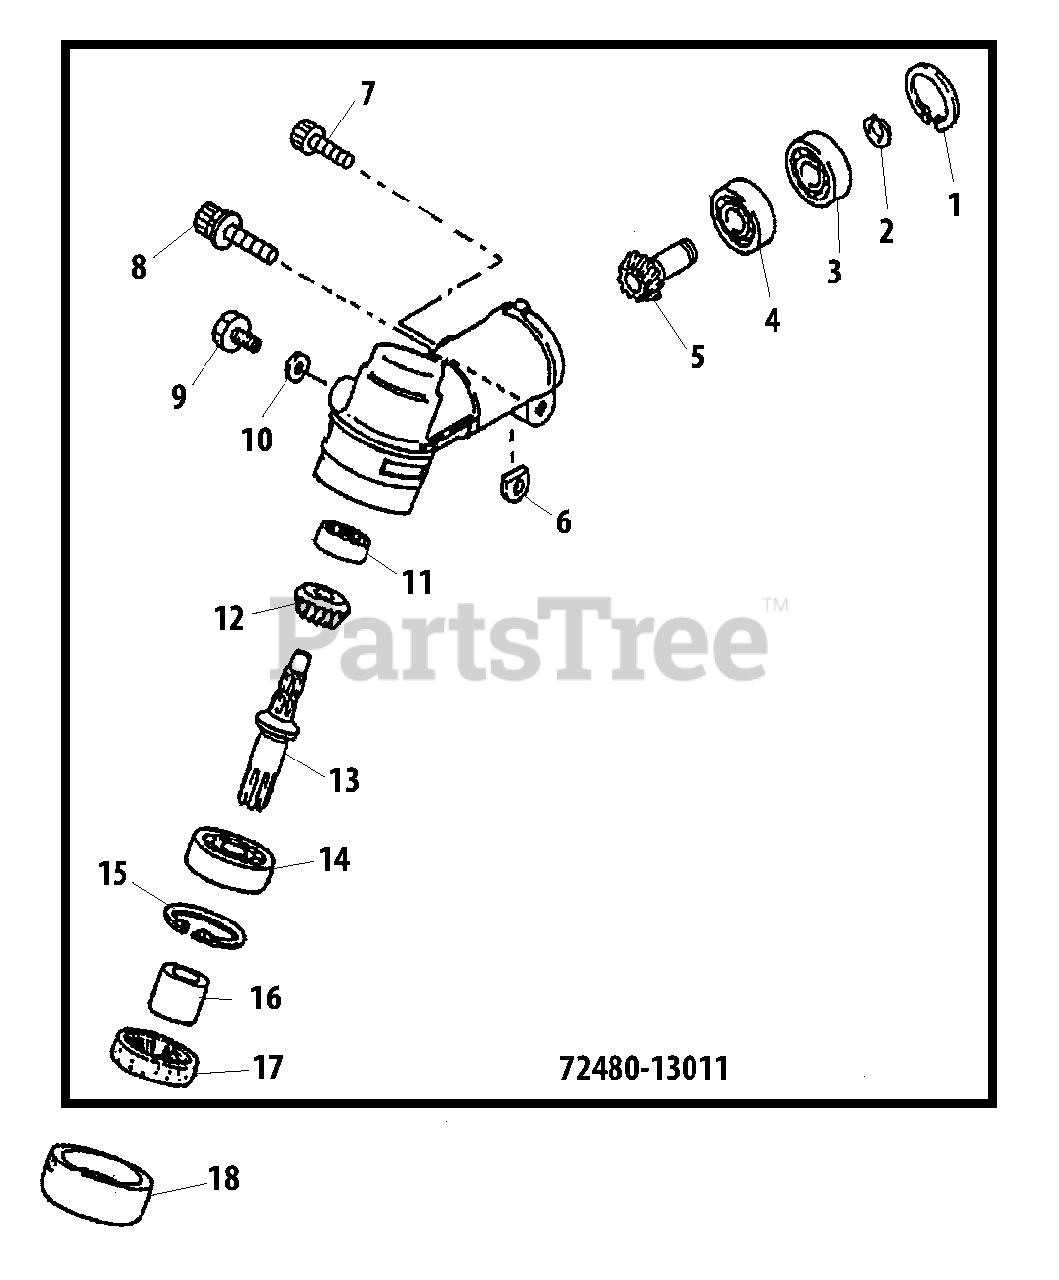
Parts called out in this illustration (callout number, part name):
1	RING, SNAP Ø22
2	RING, SNAP
3	BEARING, BALL 608ZZ
4	BEARING, BALL 608
5	GEAR, PINION
6	D-WASHER
7	BOLT 5×12
8	BOLT M5×25
9	BOLT M6×10
10	WASHER
11	BEARING, BALL 626 DDU
12	GEAR, BEVEL
13	SHAFT, GEAR
14	BEARING, BALL 6000
15	RING, SNAP Ø26
16	COLLAR
17	SEAL, OIL
18	HOLDER
72480-13011	GEAR CASE ASSY
